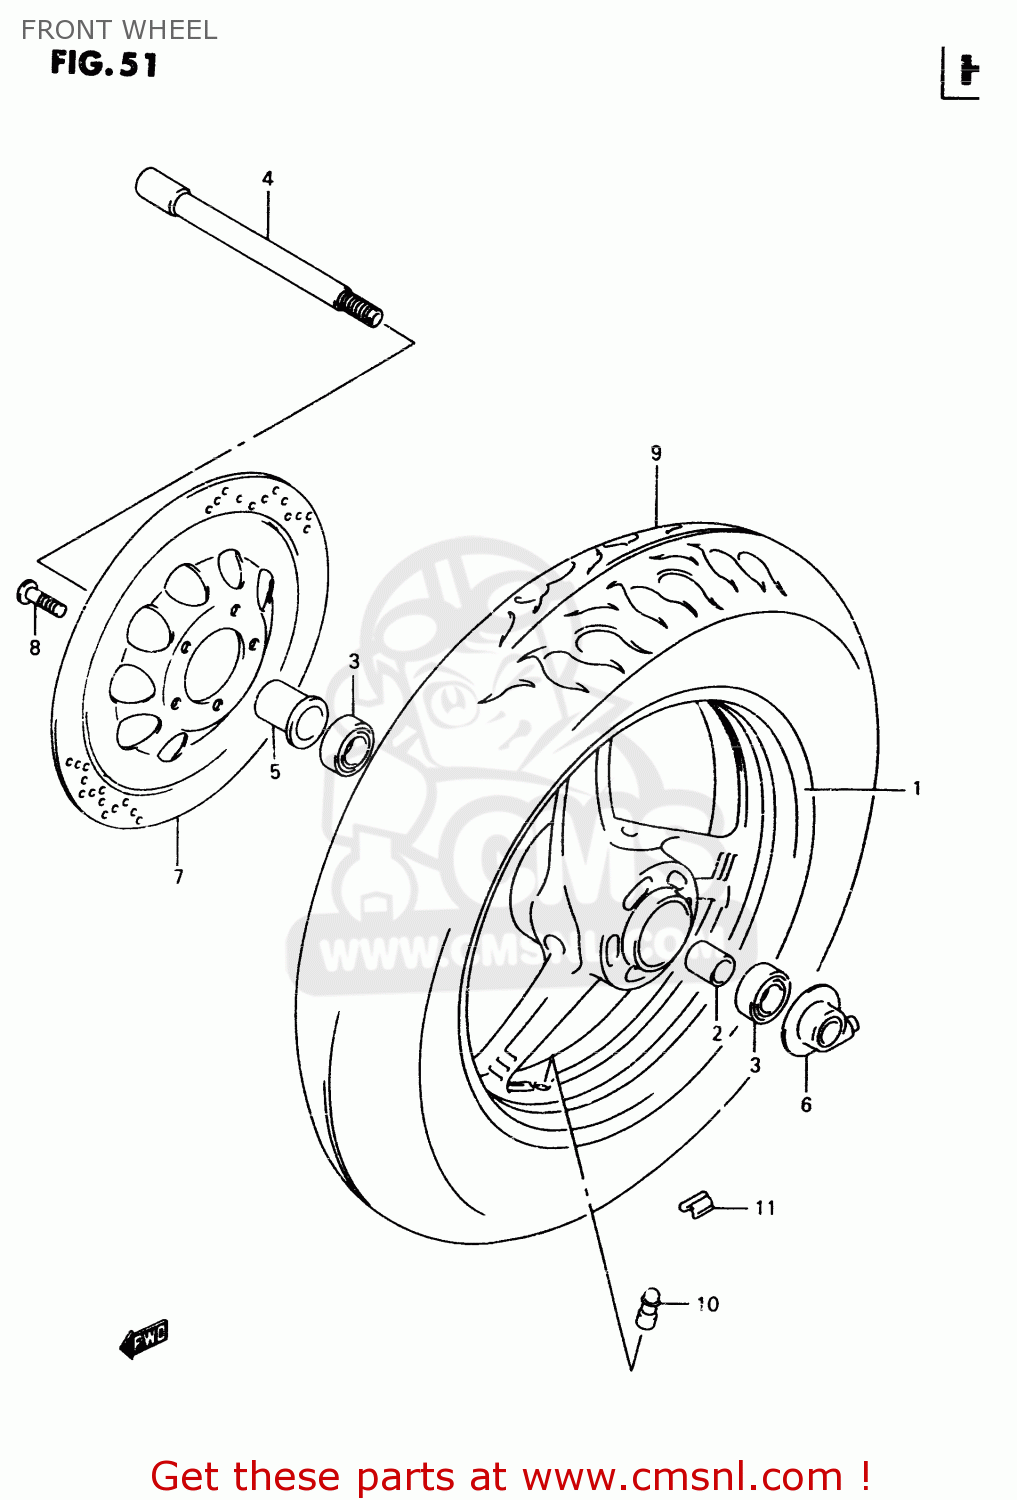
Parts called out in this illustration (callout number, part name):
1	WHEEL,FRONT (16XMT3.00)
2	SPACER(17.5X25X82.1)
3	BEARING
4	AXLE,FR
5	SPACER COMP,FRONT AXLE
6	BOX ASSY,SPEEDOMETER GEAR
7	DISC,FR BRAKE,R
8	BOLT 8X33
9	TIRE,FR(130/90-16 67H)
10	VALVE ASSEMBLY,WHEEL,TR412
11	BALANCER,WHEEL (10G)
